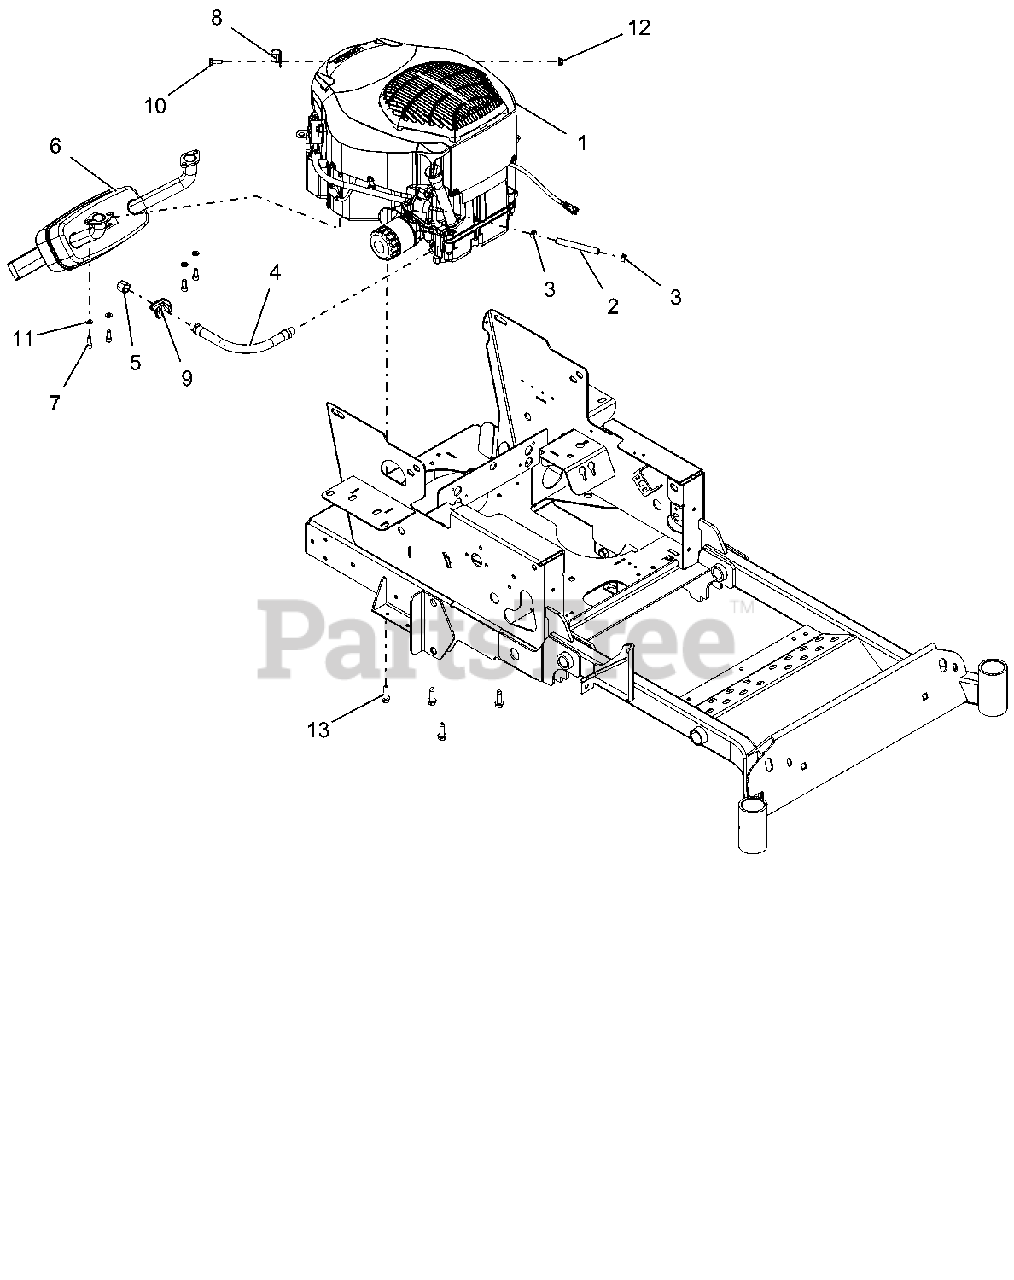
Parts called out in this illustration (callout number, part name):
1	ENGINE, KOHLER TWIN - 22HP
2	HOSE, .25 LOW-PERM BULK GAS
3	CLAMP, FUEL LINE
4	HOSE,HYD .38-11-0K M6NO-M6N0
5	PIPE CAP 3/8 NPT FEMALE
6	MUFFLER, KOHLER
7	SCR-CAP .31-18X.75 S/HD
8	CLAMP, CUSHIONED STEEL .75
9	PROTECTOR, OIL DRAIN HOSE
10	BOLT-HEX.31-18X.875 YWZC GR5
11	@WSHR-LK .31X.078 REG YWZC
12	@NUT-LK-NYL-FLG .31-18 YWZC
13	@SCR-TAP .38-16X1.25 HWH TR YZ
